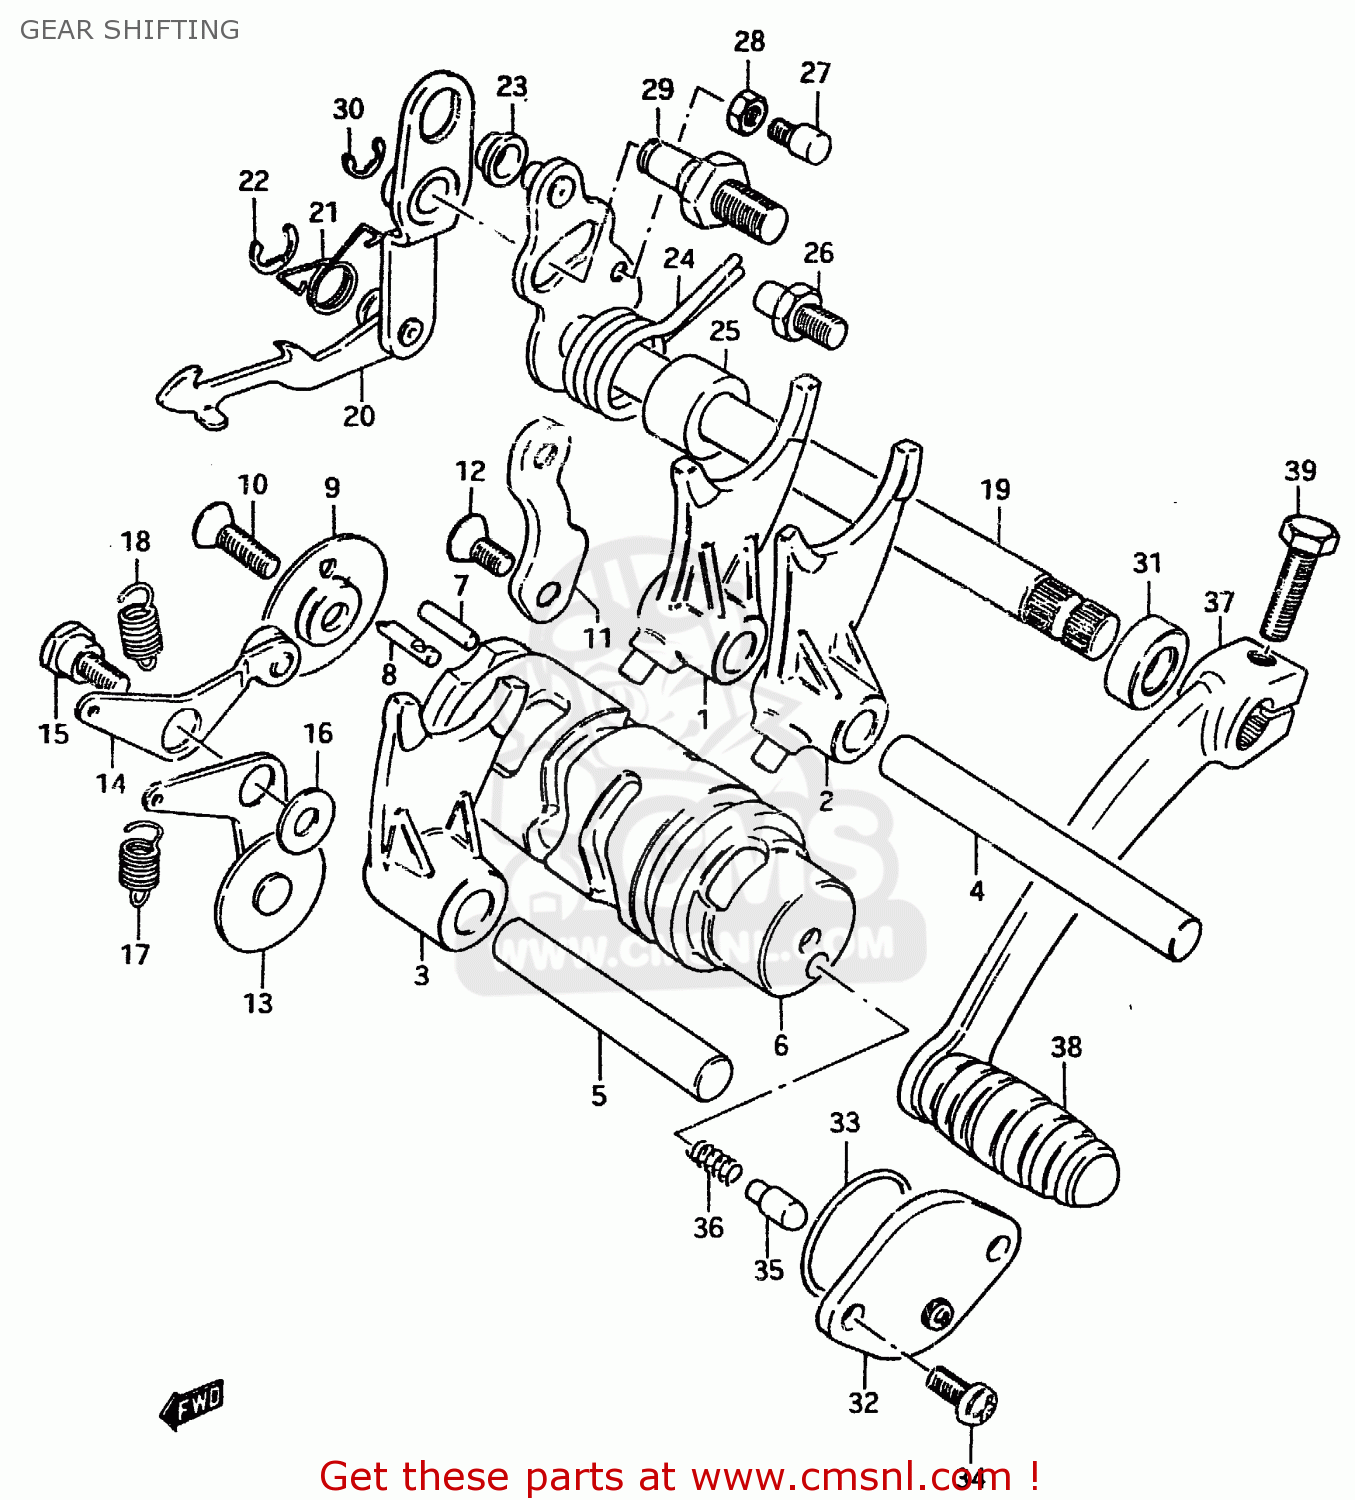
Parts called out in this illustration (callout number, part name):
1	FORK,GEAR SHIFT NO.1
2	FORK,GEAR SHIFT NO.2
3	FORK,GEAR SHIFT NO.2
4	SHAFT,GEAR SHIFT FORK
5	SHAFT,GEAR SHIFT FORK
6	CAM,GEAR SHIFT
7	PIN(4X15.8)
8	PIN
9	RETAINER,GEAR SHIFT CAM DR PIN
10	SCREW
11	GUIDE,GEAR SHIFT CAM
12	SCREW
13	STOPPER,GEAR SHIFT CAM
14	STOPPER,GEAR SHIFT CAM NEUTRAL
15	BOLT(6X18.3)
16	WASHER
17	SPRING
18	SPRING
19	SHAFT,GEAR SHIFT
20	PAWL,GEAR SHIFT
21	SPRING
22	E RING
23	SPACER(7X10X5)
24	SPRING
25	SPACER(12X20X15.3)
26	STOPPER,GEAR SHIFT CAM
27	BOLT,GEAR SHAFT RETURN SPR SET
28	NUT 6MM
29	STOPPER,GEAR SHIFT CAM
30	E RING 6MM
31	OIL SEAL
32	BODY,GEAR SHIFT SWITCH
33	O-RING (D:2.4 ID:26.2)
34	SCREW
35	PIN(5X15.5)
36	SPRING
37	LEVER ASSEMBLY,GEAR SHIFTING
38	RUBBER,GEAR SHIFT PEDAL
39	BOLT
